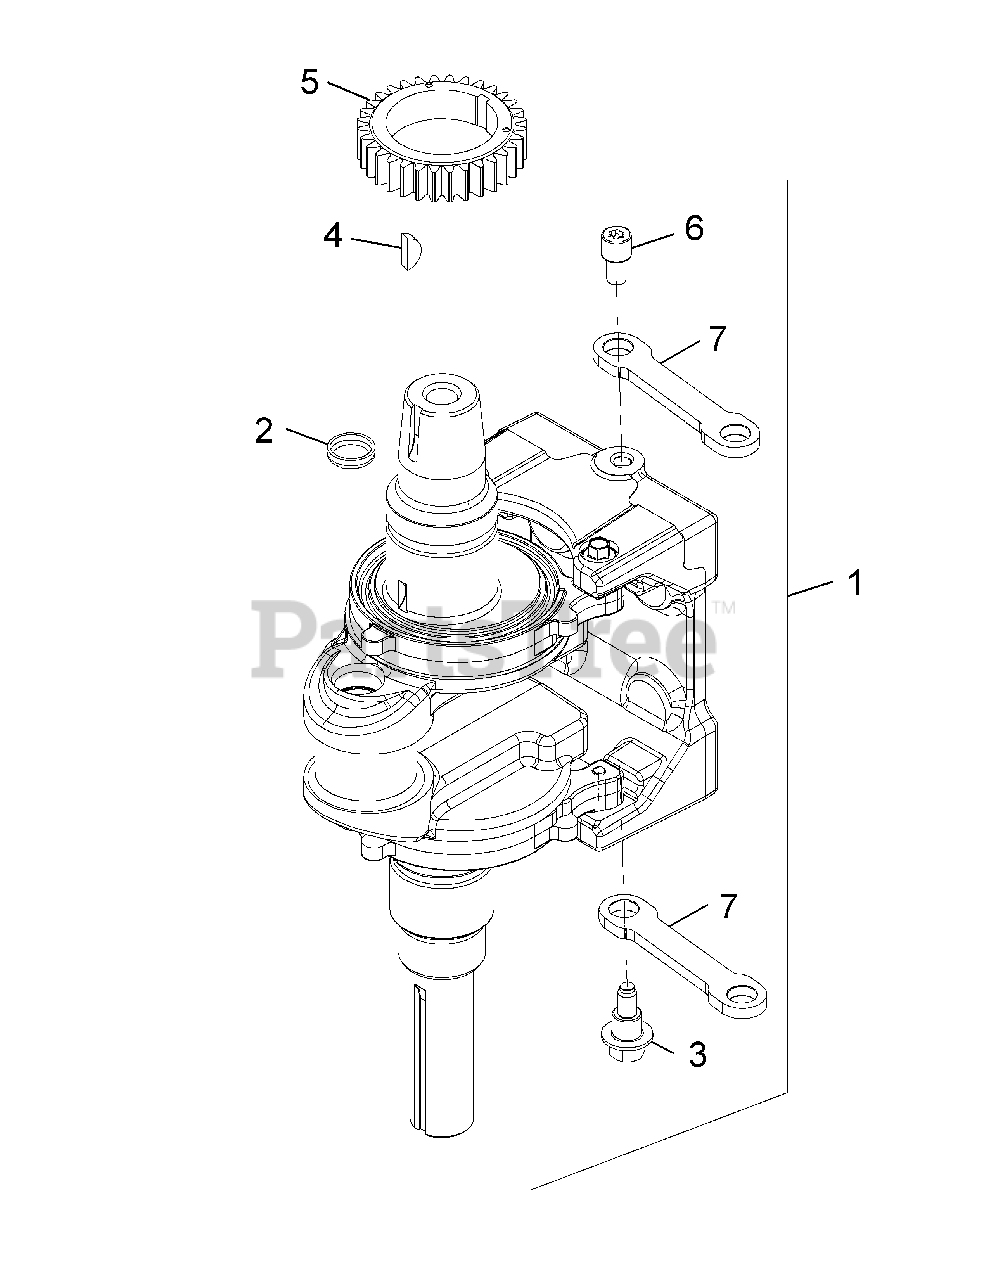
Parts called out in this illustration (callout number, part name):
1	Crankshaft Assembly Kit
3	Shoulder Screw
4	Key, 3/16 X 5/8
5	Crankshaft Gear
6	Link Pivot Screw
7	Balance Weight Linkage
